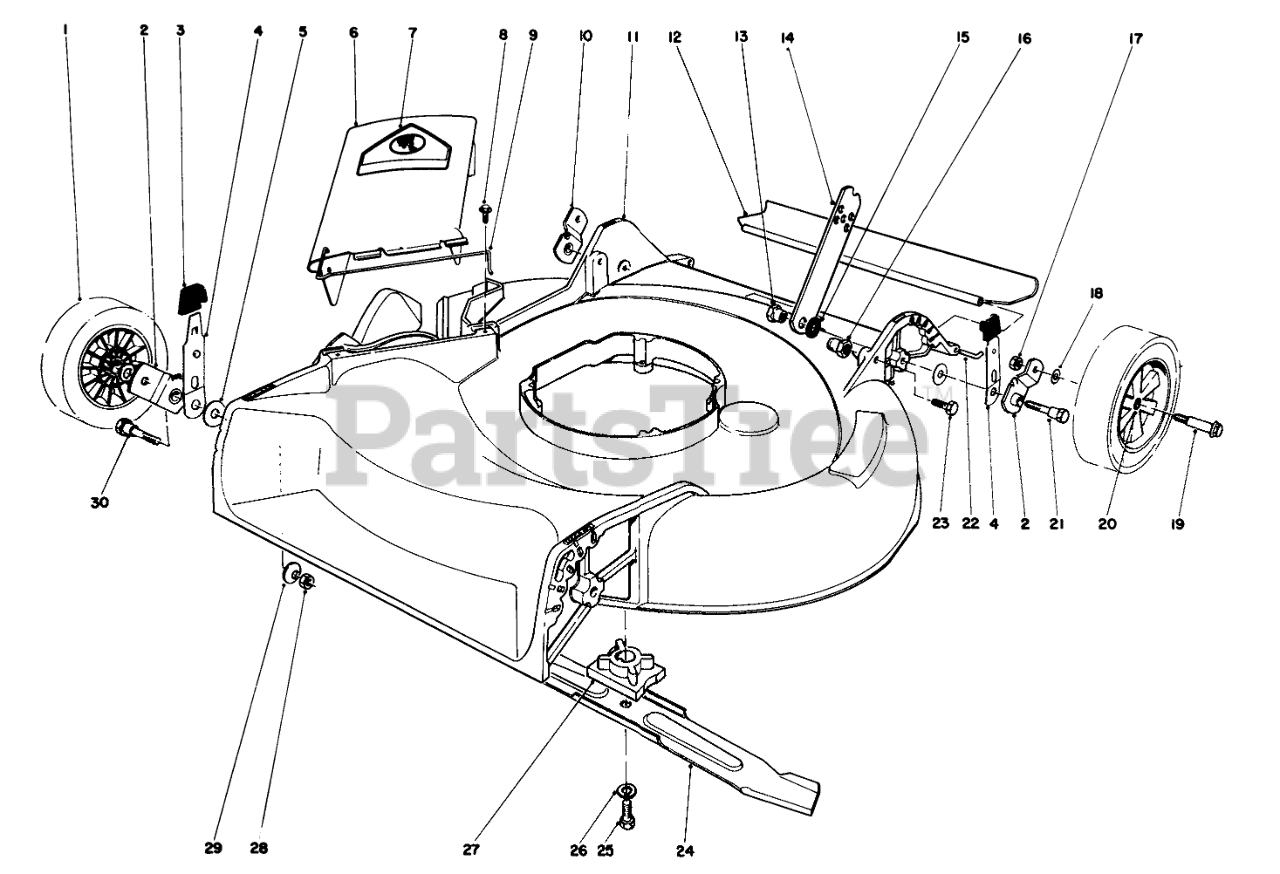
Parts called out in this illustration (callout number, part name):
1	Wheel & Tire Assembly (Incl. Ref. #20)
2	Pivot Arm
3	KNOB-ARM
4	SPRING ARM ASM
5	WASHER-PIVOT
6	Deflector Assembly (Incl. Ref. #7 & 9)
7	DECAL-DANGER
8	SCREW-HWH
9	SPRING HINGE
10	Pivot Arm
11	HOUSING/DECAL
12	REAR SAFETY SHIELD 21
13	HANDLE PIVOT NUT
14	HANDLE LATCH
15	SPACER
16	HANDLE PIVOT NUT
17	Nut
18	WASHER
19	BOLT-WHEEL
20	BUSHING
21	PIVOT SCREW
22	SHIELD ROD
23	SCREW-HH
24	Blade
25	SCREW-HH
26	WASHER-LOCK
27	BLADE RETAINER
28	NUT-LOCK, NI
29	WASHER-BELLEVILLE
30	5/16-18 PIVOT SCREW
